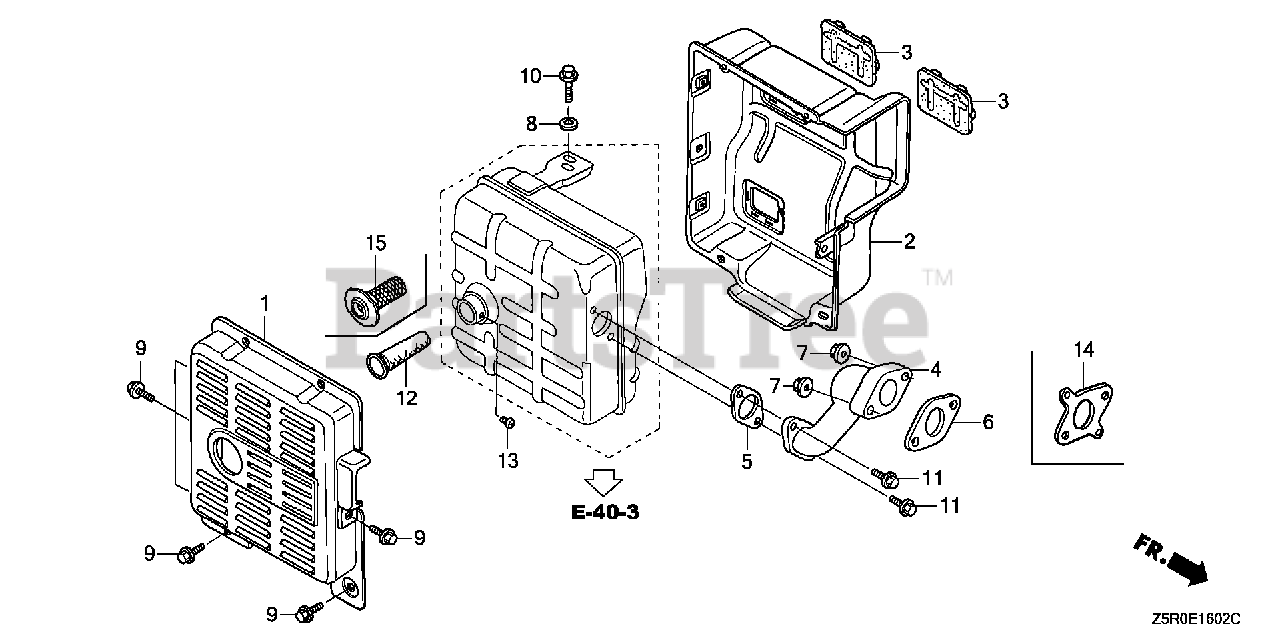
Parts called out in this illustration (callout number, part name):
7	NUT, FLANGE (8MM)
13	SCREW, TAPPING (4X6) (TO INSTALL OPTIONAL SPARK ARRESTER)
14	GASKET, EX. PIPE
15	ARRESTER, SPARK
